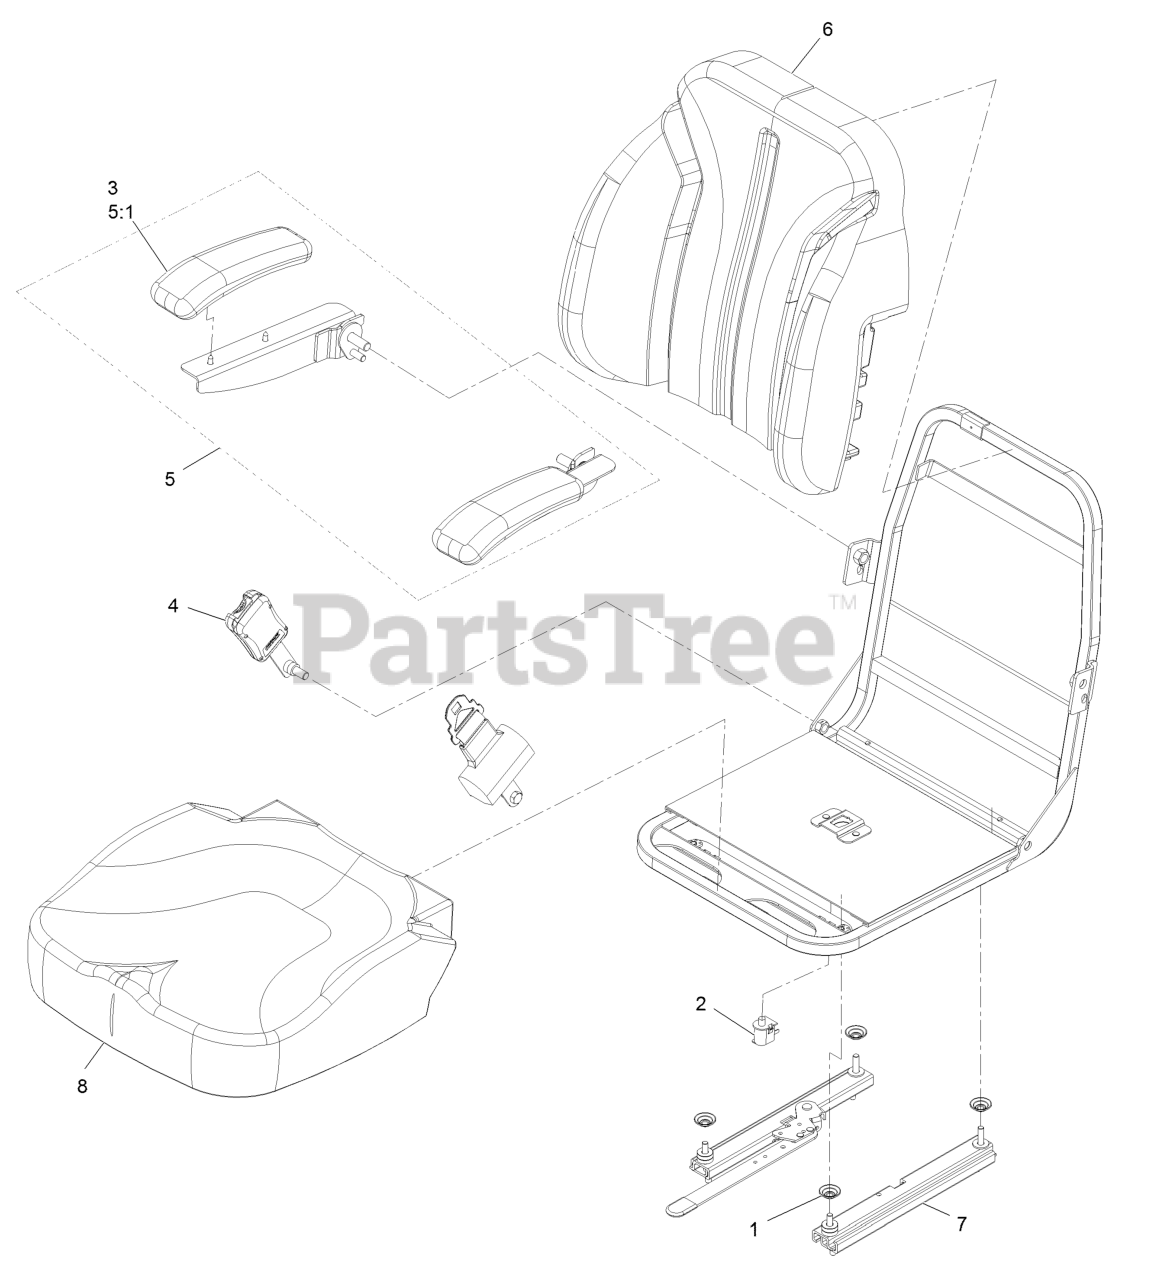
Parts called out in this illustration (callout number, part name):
1	Spacer-Mounting
3	Cushion-Rest, Arm
4	Seat Belt Kit
5	Armrest Kit
5:1	Cushion-Rest, Arm
6	Cover-Seat Back Svc
7	Track-Seat
8	Cover-Seat Bottom Svc
